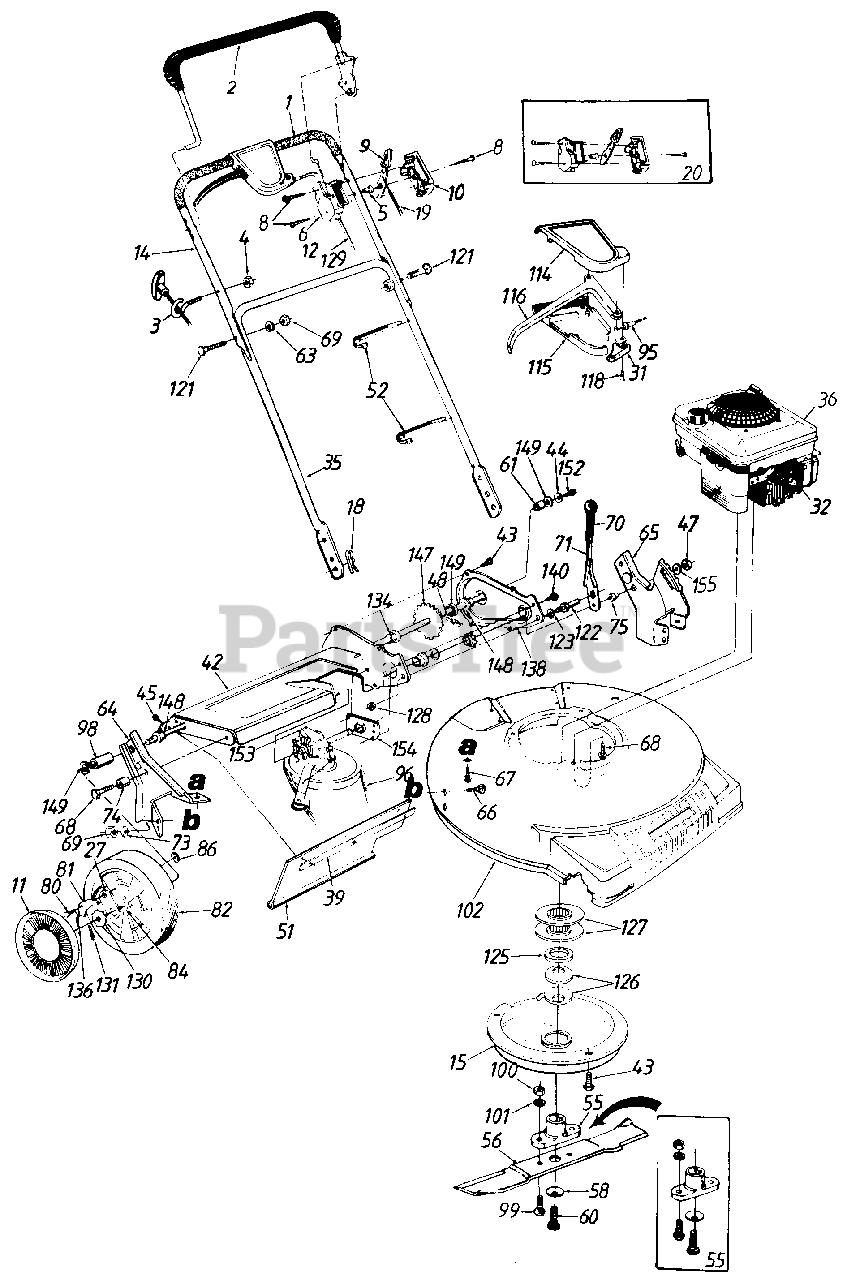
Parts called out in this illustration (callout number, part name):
1	Grip
2	Control Handle Ass'y.
3	Rope Guide Bolt
4	Hex L-Nut 1/4-20 Thd.
5	Control Disc Pin
6	Clutch Panel Half
8	Truss Mach Scr. #12 x 1.5" Lg.
9	Throttle Control Lever
10	Control Panel Half
11	Hub Cap
12	Throttle Control Label
14	Upper Handle
19	Throttle Control Wire 51" Lg.
20	Kit-Control Housing Comp.
27	Pawl Plate
31	S.P. Control Cover
32	Spark Plug Insulator
35	Lower Handle
36	Engine
39	Retaining Strip
42	Chain-Axle Ass'y.
43	Hex B-Tap Scr. 1/4" X .38"
44	Bell-Wash. 1/4" l.D.
45	Hex AB-Tap Scr. 1/4 X .62"
47	Hex Patch L-Nut 3/8-24 Thd.
48	#48 Chain .500" Pitch x 38 Links
51	Rear Flap 3.75" x 17.30" Lg.
52	Cable Tie
55	Blade Adapter Kit
56	21" Mulching Blade
58	Bell-Wash. 47" l.D. x 1.14n O.D.
60	Hex Bolt 7/16-20 x 2.5"
61	Spacer .513" l.D.
63	L-Wash. 5/16" l.D.
64	R.H. Handle Wheel Brkt. Ass'y.
65	L.H. Handle Wheel Brkt. Ass'y.
66	Carriage Bolt 5/16-18 x .62
67	Hex B-Tap Scr. 5/16-18
68	Hex TT-Tap Scr. 3/8-16
69	Hex Nut 5/16-18 Thd.
71	Height Adj. Lever
73	Bell-Wash. 5/16" l.D.
74	Spacer.383" I.D.
75	Shld. Spacer .5" Dia.
80	Shld. Scr. .342" Dia. x .268
81	Pawl
82	Wheel Ass'y. Comp.-Rear
84	Sleeve Bearing 1/2n l.D.
86	Flat Nut 1/4-20 Thd.
95	S.P. Cable-44" Lg.
96	"V"-Belt
98	Sleeve.526" I.D.
99	Hex Bolt 3/8-24 x 1.0" Lg.
100	Hex Nut 3/8-24 Thd.
101	L-Wash. 3/8" I.D.
115	Self-Propelled Control Cover
116	Control Lever
118	Fl-"C"-Sunk Hd. Tap Scr. #10 x .75n Lg.
121	Curved Carr. Bolt 5/16-18 x 1.38" Lg.
122	Shld. Pin 1.43" Lg.
123	L-Wash. 3/8" l.D.
125	Crankshaft Spacer
126	Bell-Wash. 1.01" l.D.
127	Serrated Pulley Half
128	Hex Jam Nut 3/8-24 Thd.
129	Control Cable-39"
130	Ratchet Wheel 1.62" O.D.
131	Cotter Pin 1/8" Dia. x 1
134	Hex Flange Bearing
136	0 Spring-Nylon
147	Rear Shaft Ass'y. 21.44n Lg.
148	Hex Flange Brg. .506n l.D.
149	Fl-Wash. .531" l.D. x .930"
152	Hex Bolt 1/4-20 x .62" Lg. (Grade 5)
153	Transmission Comp.
155	Fl-Wash. .885" l.D. x .87" O.D.
